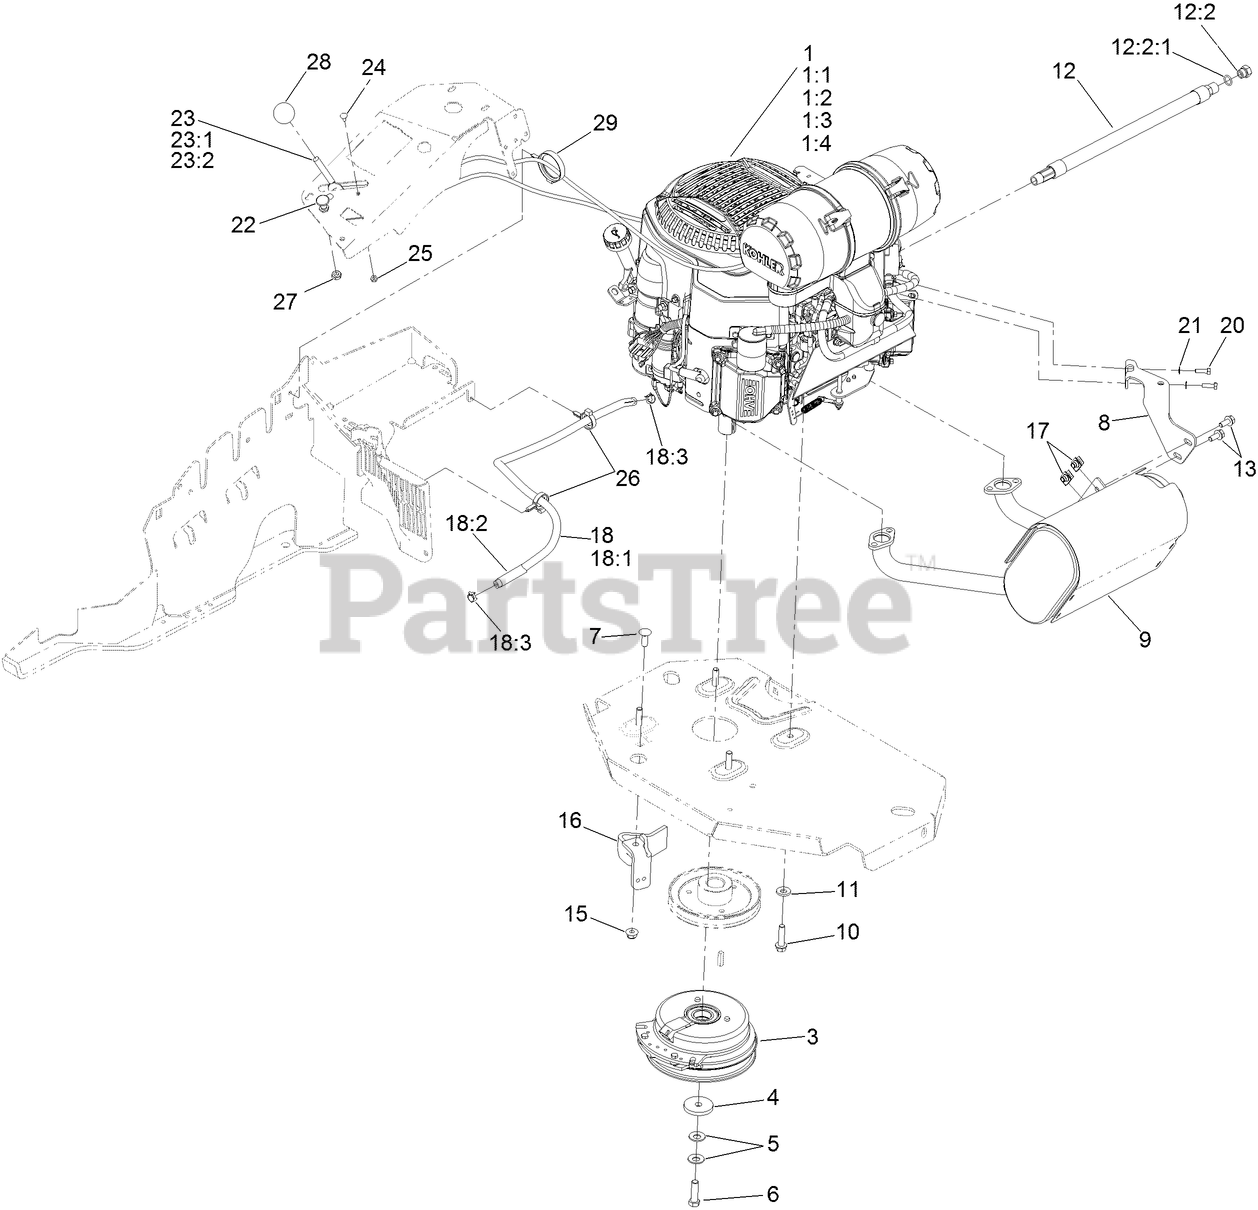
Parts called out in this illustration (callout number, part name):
1:1	KOHLER 52 050 02-S ENGINE OIL FILTER
1:2	KOHLER 25 083 01-S ENGINE AIR FILTER
1:3	KOHLER 25 083 04-S SAFETY FILTER
1:4	KOHLER 24 050 13-S FUEL FILTER
3	CLUTCH KIT
4	WASHER-CLUTCH
5	WASHER-SPRING
6	SCREW-HH, W/LOCTITE
7	SCREW-CARR
8	MUFFLER BRACKET KIT
9	MUFFLER KIT
10	SCREW-HWH
11	WASHER-BELLEVILLE
12	OIL DRAIN HOSE ASM
12:2	PLUG-HH
12:2:1	O-RING
13	SCREW-HH
15	NUT-HF, NI
16	CLUTCH-ANCHOR
17	NUT-U
18	FUEL LINE ASM
18:1	HOSE-FUEL
18:2	SLEEVE-THERMAL
18:3	CLAMP-HOSE
20	SCREW-HH
21	WASHER-SPRING
22	CHOKE CONTROL ASM
23	THROTTLE CONTROL ASM
23:1	LEVER-THROTTLE
24	BOLT-CARR
25	NUT-LOCK, NI
26	CLAMP-HOSE
27	NUT-HJ
28	KNOB-BALL
29	CLAMP-HARNESS
